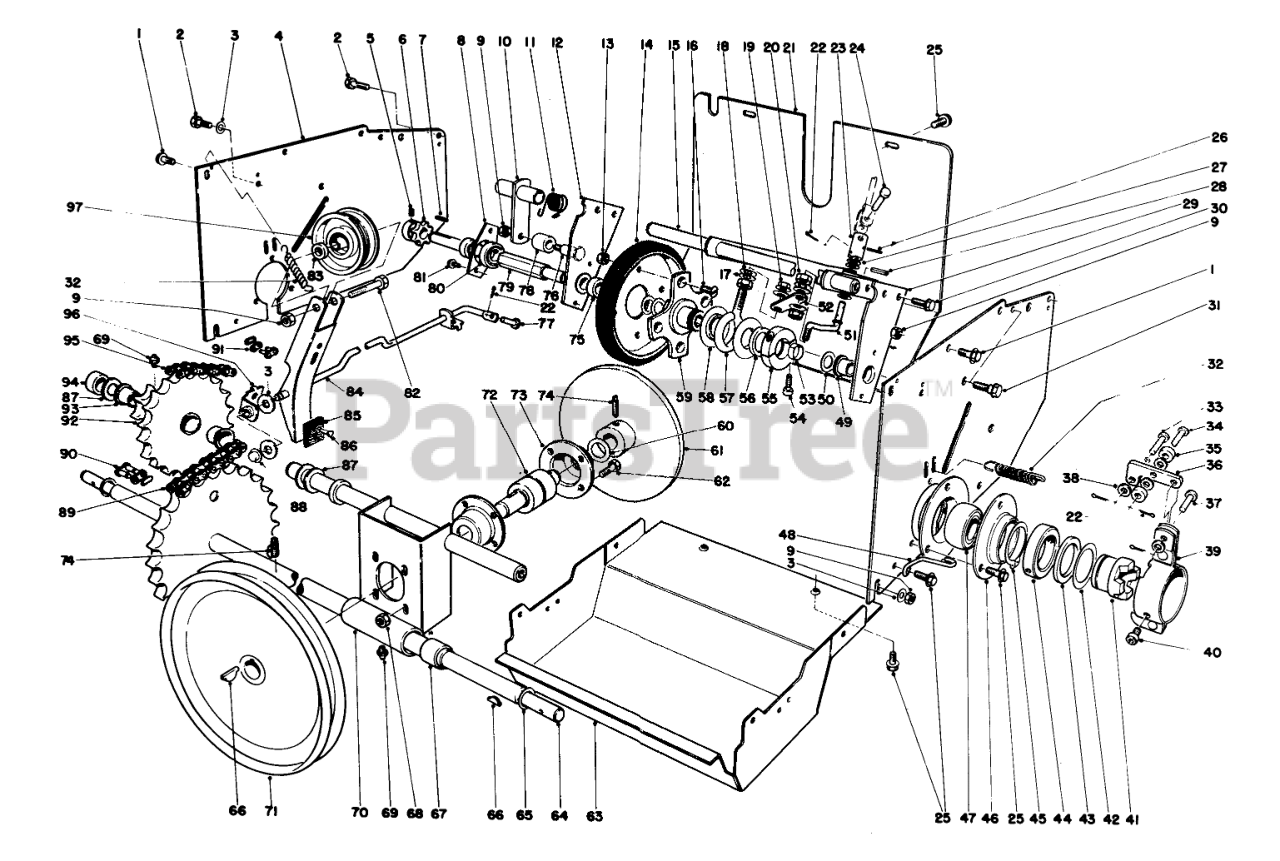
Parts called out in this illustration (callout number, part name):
1	SCREW-HHF
2	SCREW-HHFTF
3	WASHER-FLAT
4	Side Plate Drive
5	SCREW-HSH
6	SPROCKET
8	BEARING CUP
9	NUT-HEX
10	CHAIN TENSION ARM WA
11	TORSION SPRING
12	HEX SHAFT MOUNT R
13	Nut
14	Disc
15	Bracket Dead Shaft
16	5/16-18X5/8 FLT HD MS
17	WASHER-FLAT
18	WASHER-SPRING
19	NUT-LOCK, FLANGE
20	Nut
21	REAR COVER R
22	PIN-COTTER
23	U JOINT TUBE
24	CLEVIS PIN
25	SCREW-HWH
26	PIN-SPRING
27	Clevis Pin
28	PIN-ROLL
29	Hex Shaft Mount (Incl. Ref. . #49)
30	SCREW-HWHTF
31	SHOULDER SCREW
32	EXTENSION SPRING
33	PIN-CLEVIS
34	PIN-CLEVIS
35	CLUTCH ROLLER
36	CLUTCH CAM ARM
37	PIN-CLEVIS
38	WASHER-FLAT
39	CLUTCH MT BRKT ASM
40	SCREW-HSH
41	WHEEL CLUTCH
42	THRUST WASHER
43	THRUST BEARING
44	CLUTCH MOUNT COLLAR
45	RING-RETAINING, EXTERNAL
46	BEARING FLANGE
47	BEARING
48	Clutch Retainer
49	BUSHING
50	WASHER-FLAT
51	CONNECTION ROD
52	SHIFT ROD PIVOT
53	SPLIT SPACER
54	SCREW-HSH
55	ColIar
56	WASHER-THRUST
57	SLIDER RING COLLAR
58	SLIDER RING
59	TRACTION DISC HUB
60	Spacer
61	Friction Plate
62	SCREW-HH
63	LOWER SHIELD R
64	AXLE SHAFT WA
65	Washer
66	KEY-WOODRUFF
67	BUSHING
68	NUT-KEPS
69	FITTING-GREASE
70	Bulkhead (Incl. Ref. #67)
71	Pulley
72	BEARING-FRICTION PLATE
73	HOUSING BEARING
74	SCREW-SET, SQH
75	SPACER
76	Shoulder Bolt
77	PIN-CLEVIS
78	CHAIN TENSION ROLLER
79	FRICTION WHEEL SHAFT
80	BEARING
81	SCREW
82	SCREW-HH
83	Spacer
84	Auger Idler (Incl. Ref. #85-86)
85	BRAKE PAD
86	.185 DIA X .375 RT +
87	WASHER-THRUST
88	PUSH NUT
89	ROLLER CHAIN
90	LINK-CHAIN
91	LINK-CONNECTING
92	Sprocket (Incl. Ref. #69 & 93)
93	3/4ID X 3/4LG BSHG
94	SPACER-IDLER
95	1/4 X 42 CHAIN W/LINK
96	Bracket-Clutch
97	PULLEY-IDLER
